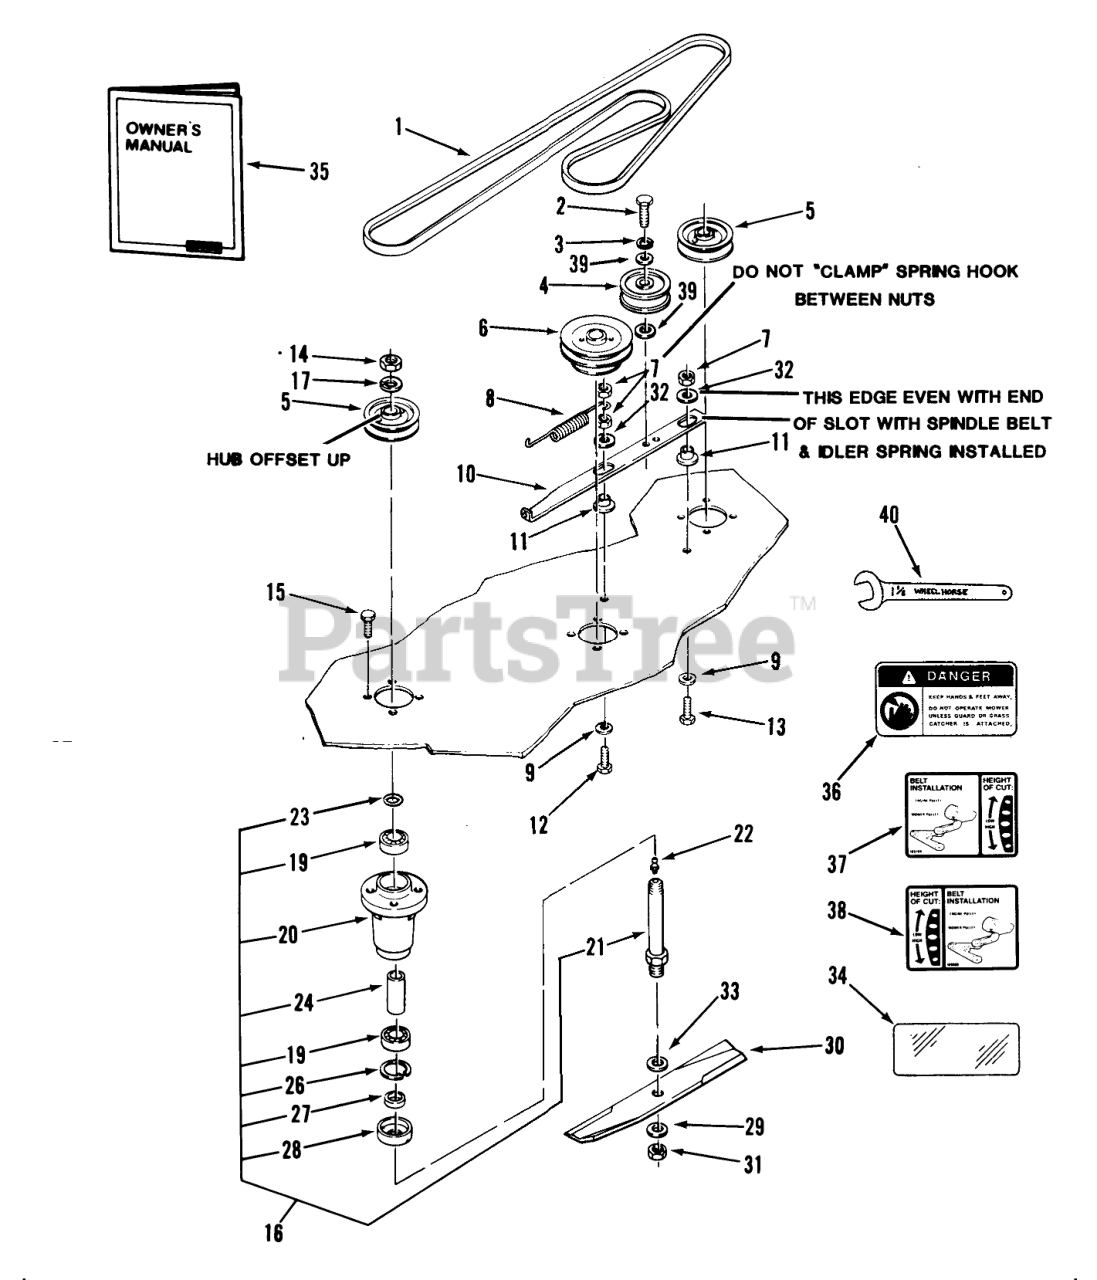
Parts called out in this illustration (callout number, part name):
1	V-BELT
1	V BELT
2	Bolt
3	LOCKWASHER
4	Pulley
4	Idler Pulley
5	PULLEY-BLADE, DRIVE
5	PULLEY
6	PULLEY-MOWER, 48IN
6	PULLEY
7	NUT
8	SPRING-EXTENSION
9	WASHER
10	BAR-IDLER SUPPORT
11	SPACER-BUSHING
12	Bolt
13	Bolt
14	Jam Nut 5/8-18
15	Bolt
16	Spindle Assembly
17	Lockwasher
19	BEARING-BALL
20	HOUSING-SPINDLE
21	SHAFT-SPINDLE
22	Zerk
23	O RING
26	Ring-Snap
27	SPACER-BLADE
28	CUP-SPINDLE
29	Washer
30	BLADE KIT (3 PACK)
30	14IN BLADE KIT
30	BLADE KIT
31	Nut-Jam
32	WASHER
33	Washer
33	SpeciaI Washer
34	DECAL-OVERLAY
35	Operator-s Manual
36	Danger Decal
37	DECAL-HEIGHT & BELT
38	DECAL-HEIGHT & BELT
39	Washer
40	Spindle Wrench
